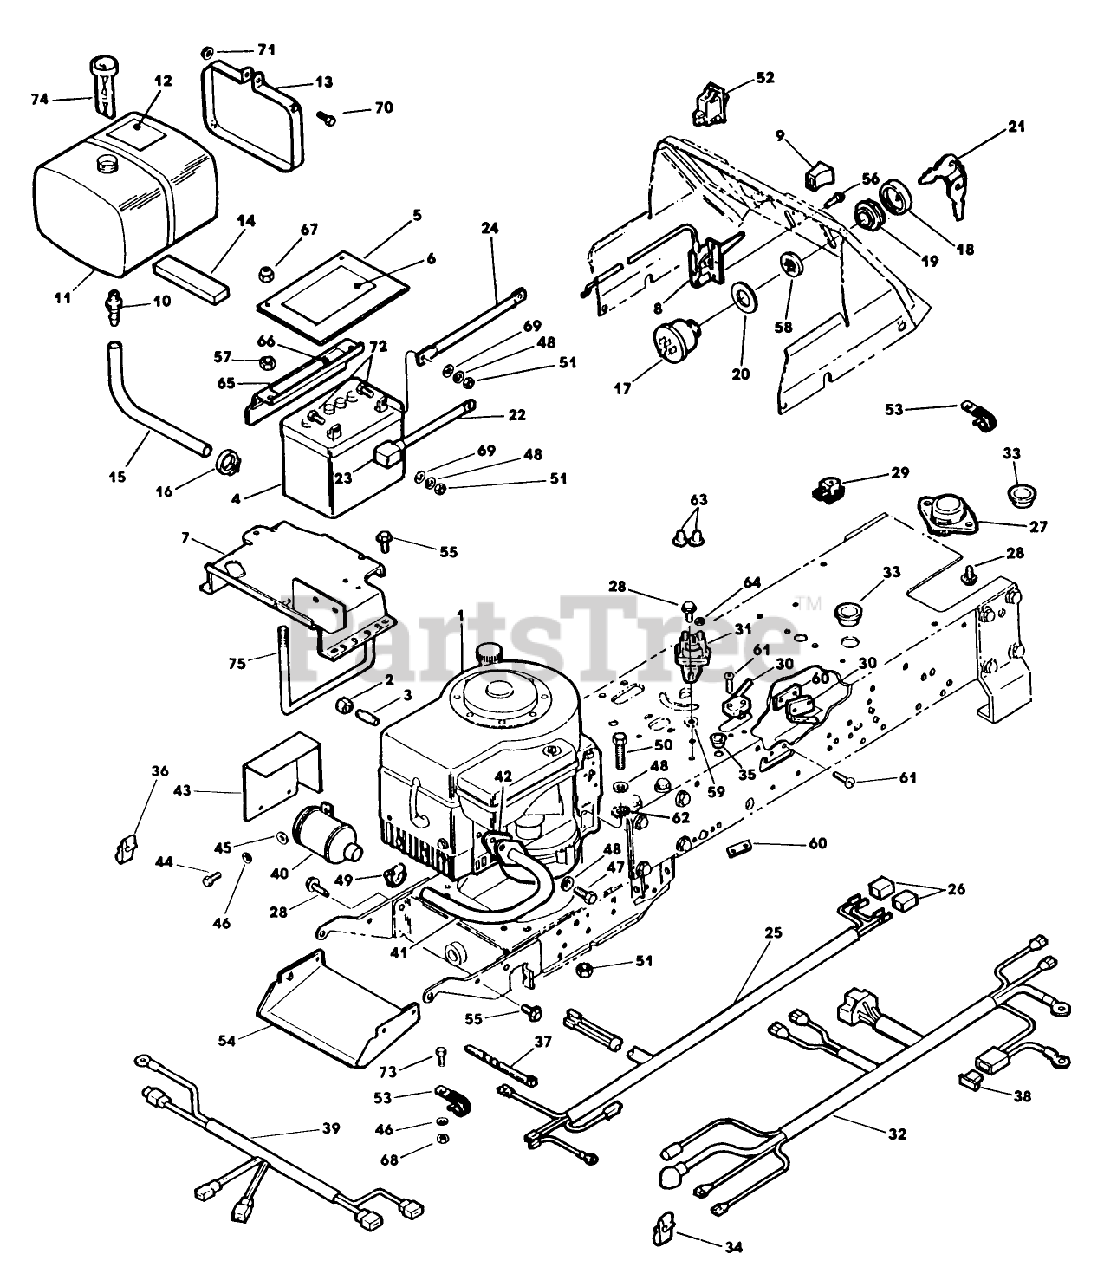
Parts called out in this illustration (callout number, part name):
5	BATT. CVR & R/B 744648
9	THROTTLE KNOB
15	HOSE
18	BEZEL
19	NUT
20	WASHER
21	KEY
22	CABLE ASSEMBLY
27	SWITCH
29	SWITCH,SEAT
30	SWITCH
31	SOLENOID
36	CLIP-RETAINER, WIRE
40	MUFFLER AY
42	GASKET
44	SCREW
51	NUT SS
52	SWITCH ASSEMBLY
64	NUT-HEX
65	HOLD DOWN & DECAL (12)
67	NUT-LOCK, CONE
68	NUT
72	SCREW - HEX
74	FUEL CAP&GUAGE AY.
